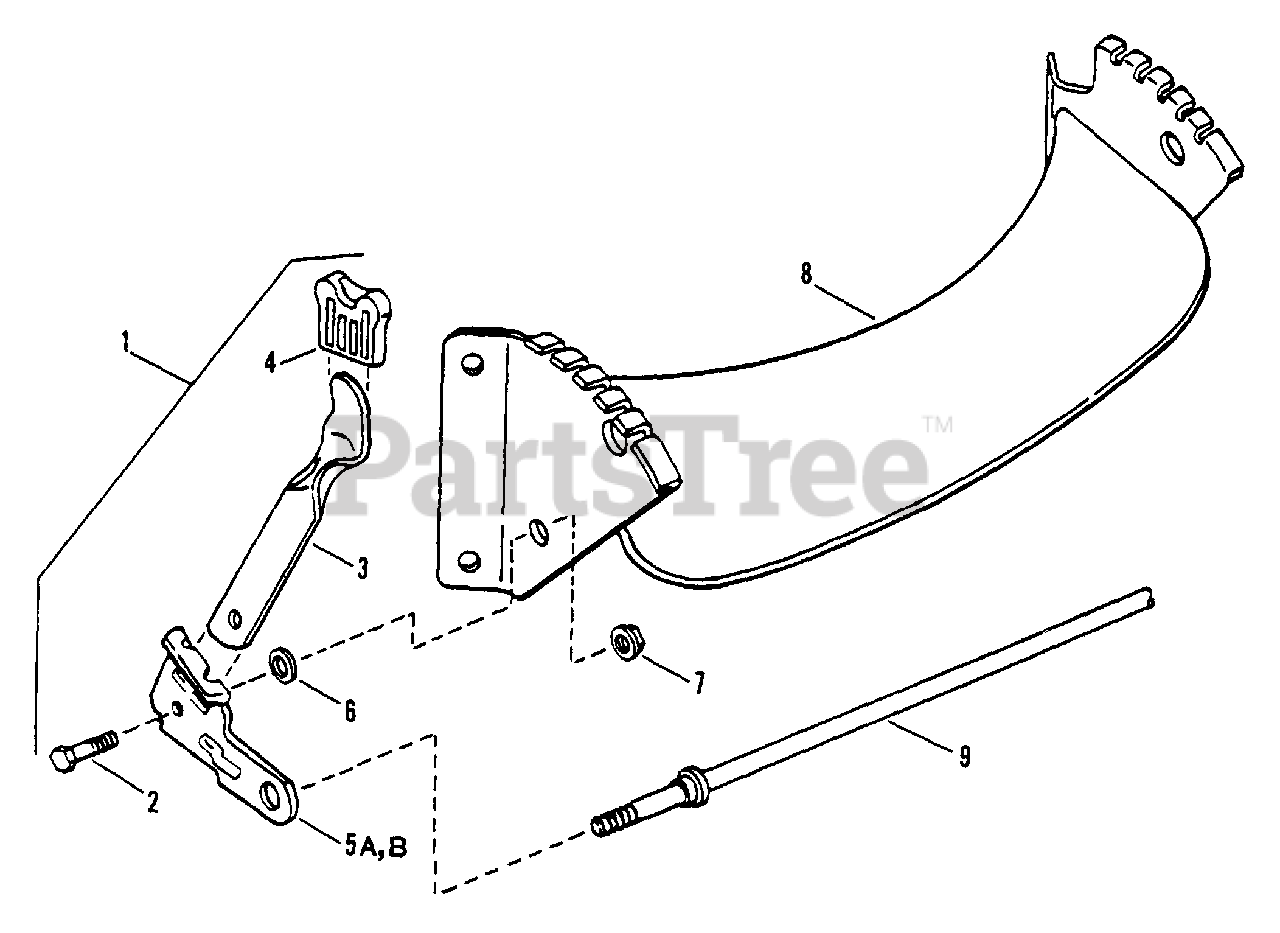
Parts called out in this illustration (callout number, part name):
1	ASSEMBLY, Arm Left Wheel (Square hole)
2	BOLT, 5/16-18 x 3/4" Shoulder
3	LATCH, Height
4	GRIP, Latch
5A	ARM, Left Wheel (Square hole)
5B	ARM, Right Wheel (Round Hole)
6	RETAINER, 5/16 Bolt
7	NUT, 5/16-18 Hex Flange Lock, Grade 5
8	BRACKET, Front Wheel
9	AXLE
